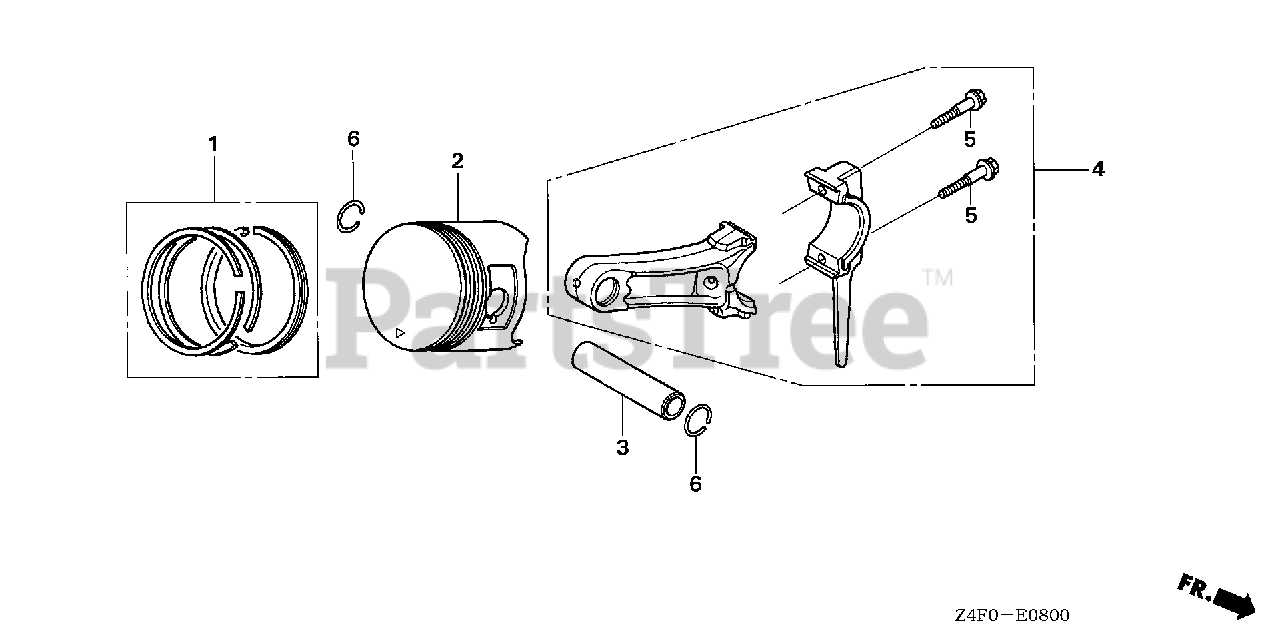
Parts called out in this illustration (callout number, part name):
1	RING SET, PISTON (STD) (TEIKOKU)
1	RING SET, PISTON (STD) (NIPPON)
1	RING SET, PISTON (0.25) (TEIKOKU)
1	RING SET, PISTON (0.25) (NIPPON)
1	RING SET, PISTON (0.50) (TEIKOKU)
1	RING SET, PISTON (0.50) (NIPPON)
1	RING SET, PISTON (0.75) (TEIKOKU)
1	RING SET, PISTON (0.75) (NIPPON)
2	PISTON (STD)
2	PISTON (0.25)
2	PISTON (0.50)
2	PISTON (0.75)
3	PIN, PISTON
4	ROD ASSY., CONNECTING
5	BOLT, CONNECTING ROD
6	CLIP, PISTON PIN (13MM)
